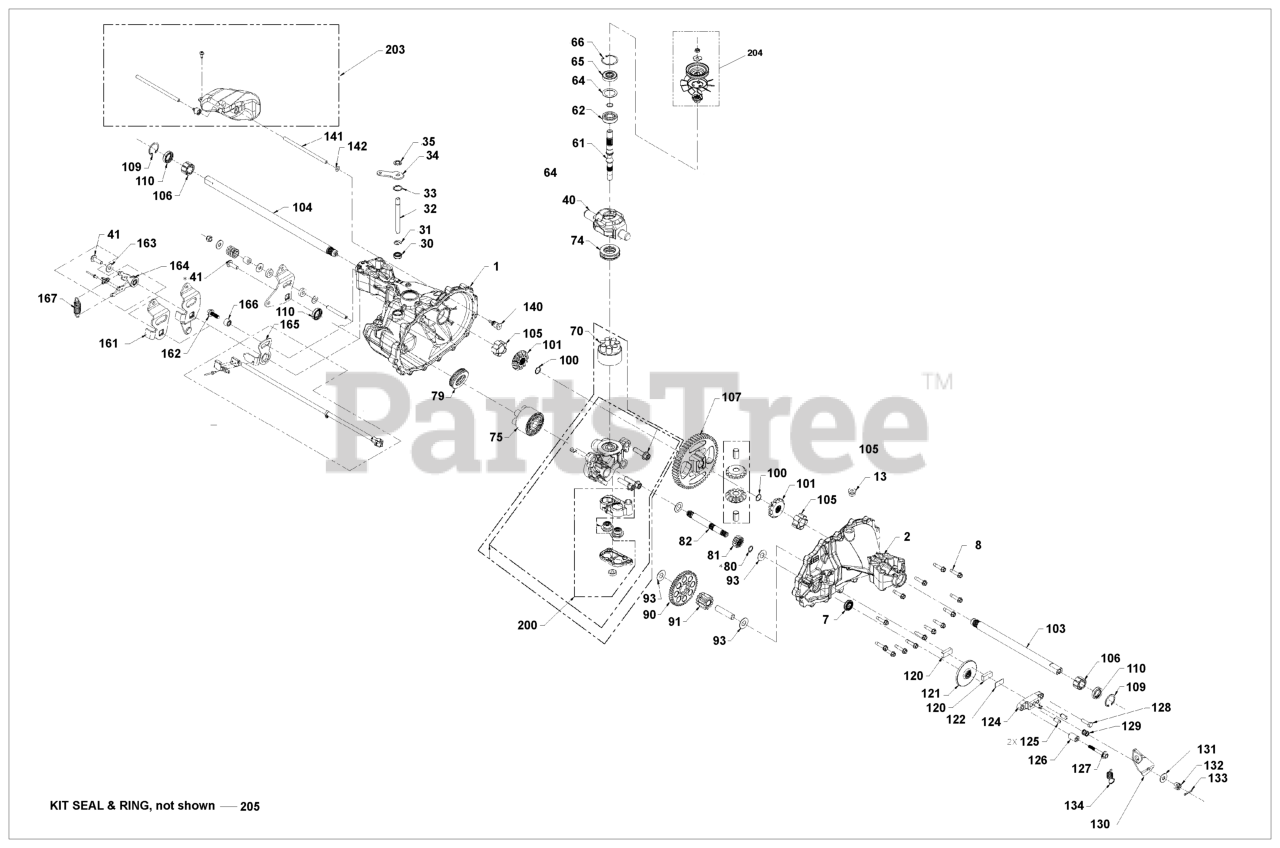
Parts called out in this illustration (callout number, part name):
62	BALL BEARING
75	KIT CYLINDER #70331
80	SEAL LIP
109	RETAINER.RING.INT.AXLE
122	PUCK PLATE 44134
125	BRAKE PIN 44127
128	BOLT W/NYLOCK 44433
131	WASHER FLAT
163	WASHER FLAT
